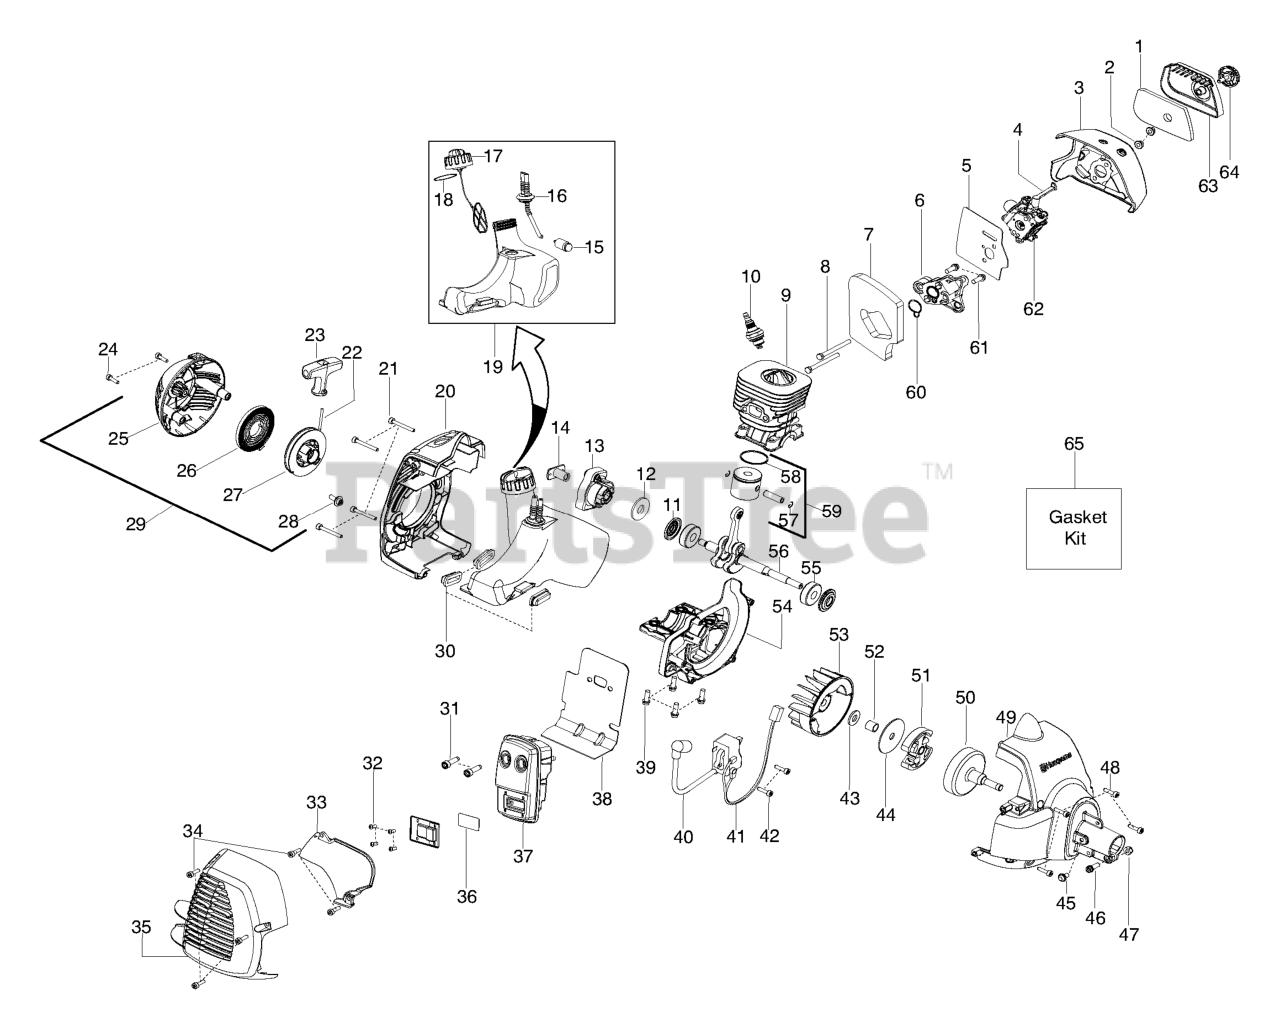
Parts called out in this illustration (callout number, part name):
1	FILTER AIRBOX
3	RP_AIR BOX
4	CHOKE LEVER
5	KIT GASKET CARB
6	CARB ADAPTOR
7	KIT GASKET 28CC TRIMMER
8	BOLT CARB ADAPTOR
9	CYLINDER
10	Plug-Spark
11	KIT SEAL CRANKSHAFT
12	WASHER FLAT
13	ASSY-STARTER CUP
14	COUPLING-STARTER
15	FUEL PICK-UP ASSY
16	KIT FUEL LINE
17	ASSY-CAP W/RETAINER
18	O RING NITRILE
19	%FUEL TANK ASSY
20	REAR SHROUD
23	STARTER HANDLE GRAY
24	SCREW M5-0.8X30MM
25	STARTER HOUSING
26	%KIT STARTER SPRING
27	KIT STARTER PULLEY
29	ASSY-STARTER HSG.
30	ISOLATOR FUEL TANK
31	BOLT MUFFLER
32	SCREW-10-16 X 1/2 HI-LO
33	SHIELD HEAT
34	SCREW M4 X 1.75 PT 16MM
35	GUARD-MUFFLER
36	KIT SPARK ARRESTOR SCREEN
37	ASSY-MUFFLER
38	GASKET PAPER METAL
39	SCREW-M5-0.8 X 25MM(TAP)
40	IGNITION MODULE MB45
41	ASSY MODULE LEAD WIRE
42	SCREW M4 X .70 TT 16MM
44	WASHER-CLUTCH
47	NUT HEX LOCK 10-24
48	SCREW M4 X .70 TT 16MM
49	FAN HSG ASSY
50	ASSY-CLUTCH DRUM
51	%KIT CLUTCH ASSY
52	SPACER FLYWHEEL
54	CRANKCASE CASTING
55	BEARING RADIAL BALL (6201)
56	KIT CRANKSHAFT ASSY
57	WRIST PIN RET.
58	RING PISTON
59	KIT PISTON 28CC TRIMMER
60	KIT GASKET 28CC TRIMMER
61	SCREW-M5-0.8 X 25MM(TAP)
62	KIT CARBURETOR
63	COVER-AIR BOX
64	KNOB ASSY AIRBOX COVER
65	KIT GASKET 28CC TRIMMER
